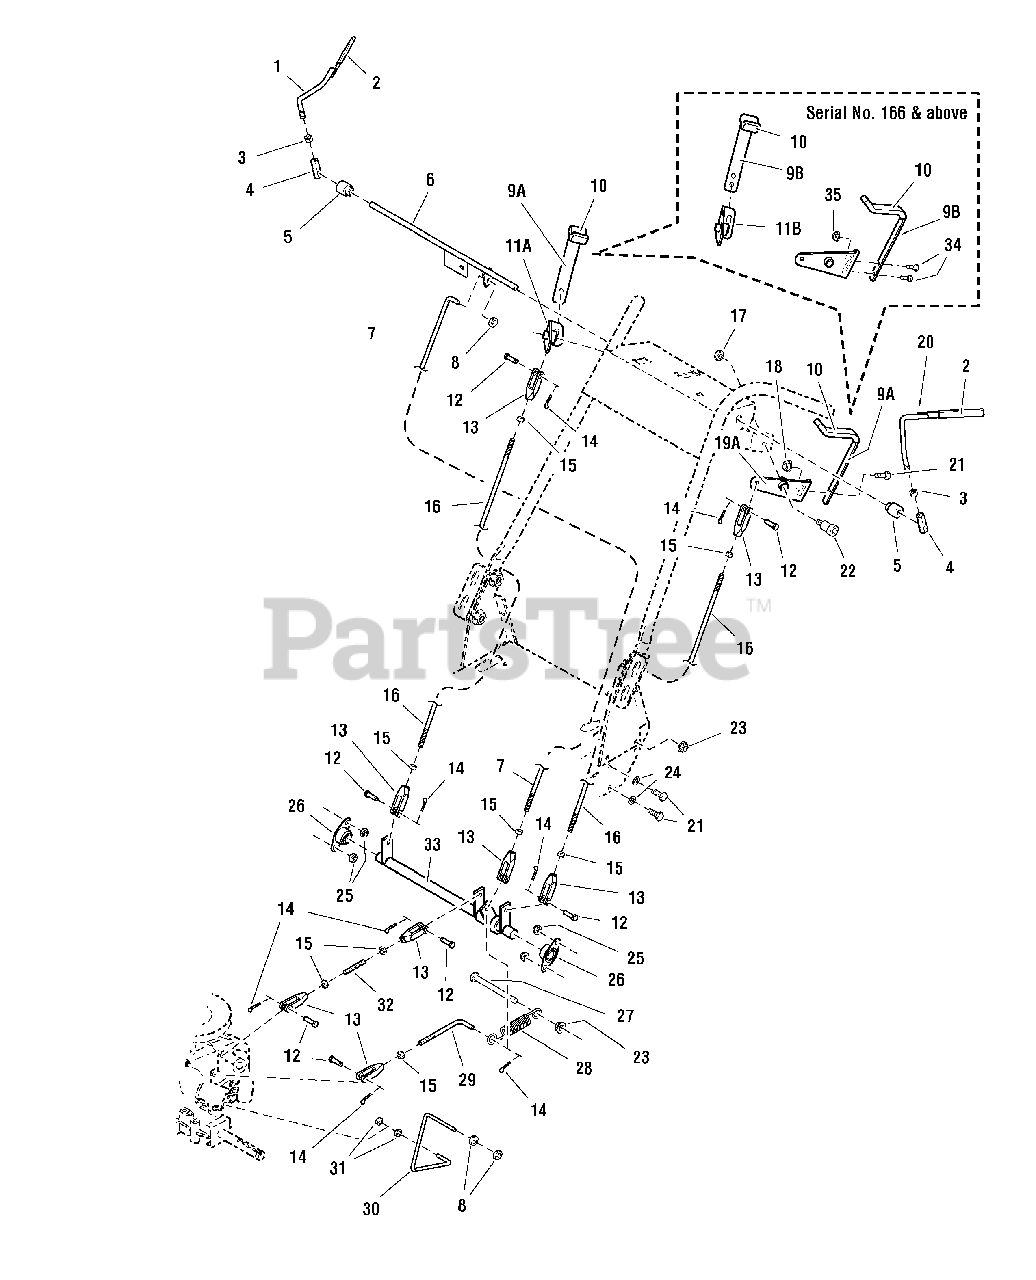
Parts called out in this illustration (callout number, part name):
1	OPERATOR PRESENCE HANDLE - RH, Complete (includes Ref 2)
3	NUT, Hex, 3/8-16
4	ADJUSTER LINKAGE
5	SHOULDER SPACER
8	COLLAR, Set, 5/16
9A	THUMB CONTROL LEVER, Complete (includes Ref No. 10) (S/N: 101-165)
9B	THUMB CONTROL LEVER, Complete (includes Ref No. 10) (S/N: 166 & up)
11A	PIVOT CONTROL - RH (S/N: 101-165)
11B	PIVOT CONTROL - RH (S/N: 165 & up)
12	PIN, Clevis, 5/16 x 1
13	CLEVIS, Plastic, 5/16-24
14	PIN, Cotter
15	NUT, Hex, 5/16-24
16	THUMB CONTROL ROD
17	NUT, Hex, Side Lock, 3/8-16
18	NUT, Hex Serrated Flange, 5/16-18
19A	PIVOT CONTROL - LH (S/N: 101-165)
19B	PIVOT CONTROL - LH (S/N: 166 & up)
20	OPERATOR PRESENCE HANDLE - LH, Complete (includes Ref 2)
21	CAPSCREW, Hex Head, 5/16-18 x 3/4
22	SHOULDER BOLT, 1/2 x 1
23	NUT, Hex Serrated Flange, 3/8-16
24	WASHER, 5/16
25	NUT, Hex Nylon Lock, 5/16-18
26	BEARING, Flange
27	CAPSCREW, Hex Head, 3/8-16 x 4
28	SPRING, Extension
29	BRAKE LINKAGE ROD
30	DUMP VALVE ROD
31	COLLAR, Set, 1/4
33	CONTROL SHAFT ASSEMBLY
34	CAPSCREW, Hex Head, 1/4-20 x 3/4
35	NUT, Hex Serrated Flange, 1/4-20
